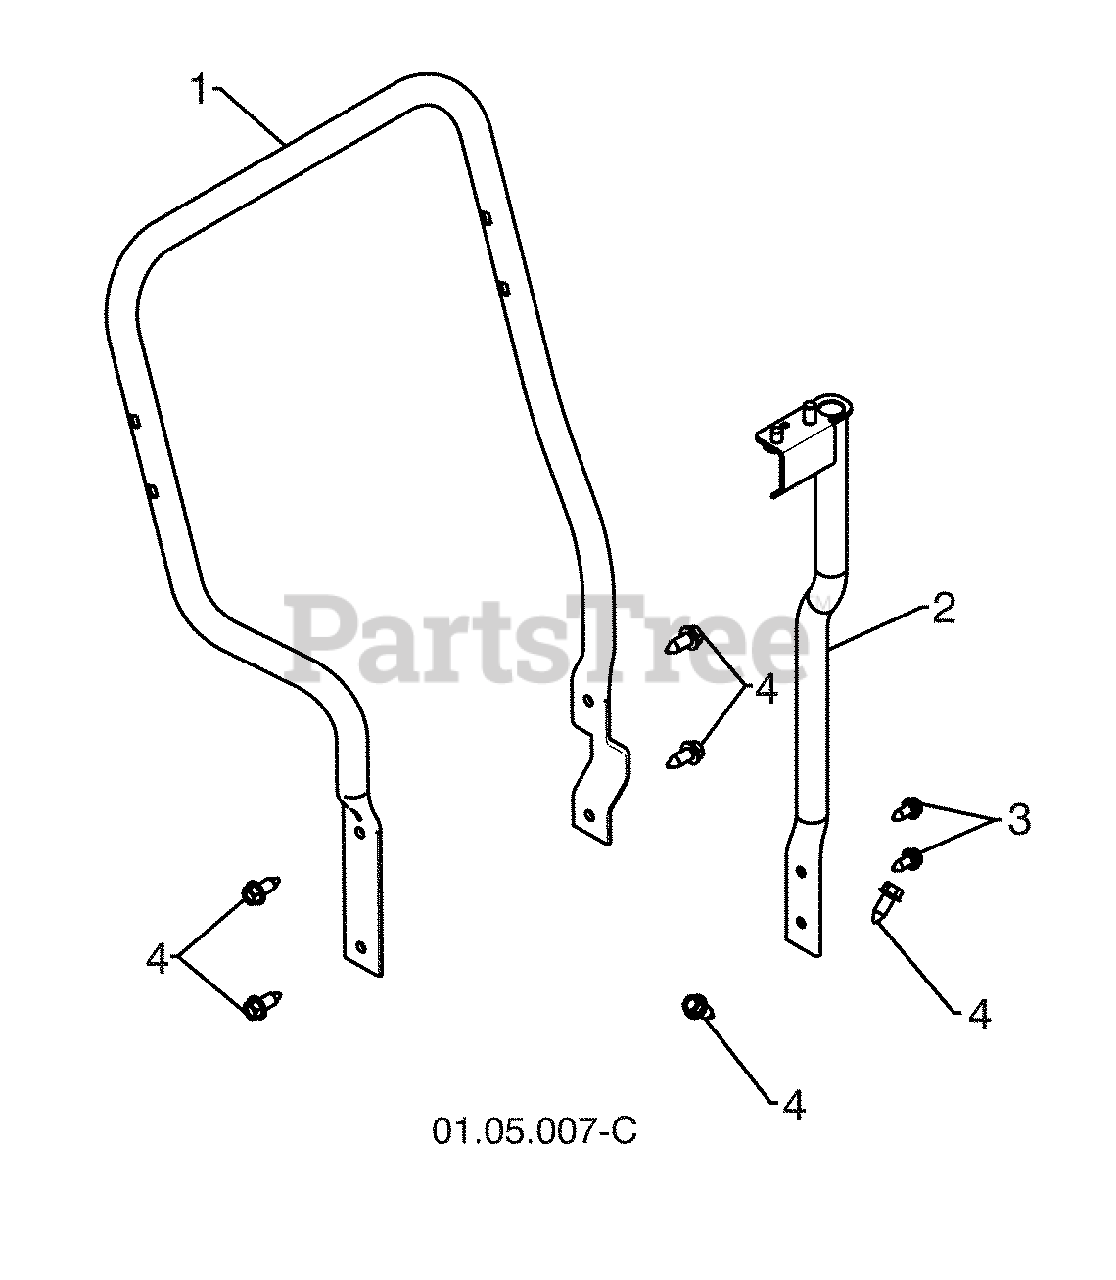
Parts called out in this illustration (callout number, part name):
1	LOWER TUBE
2	PIVOT SUPPORT
3	BOLT 5/16-18 X .750
4	SCREW 3/8-16 X 1 .00
